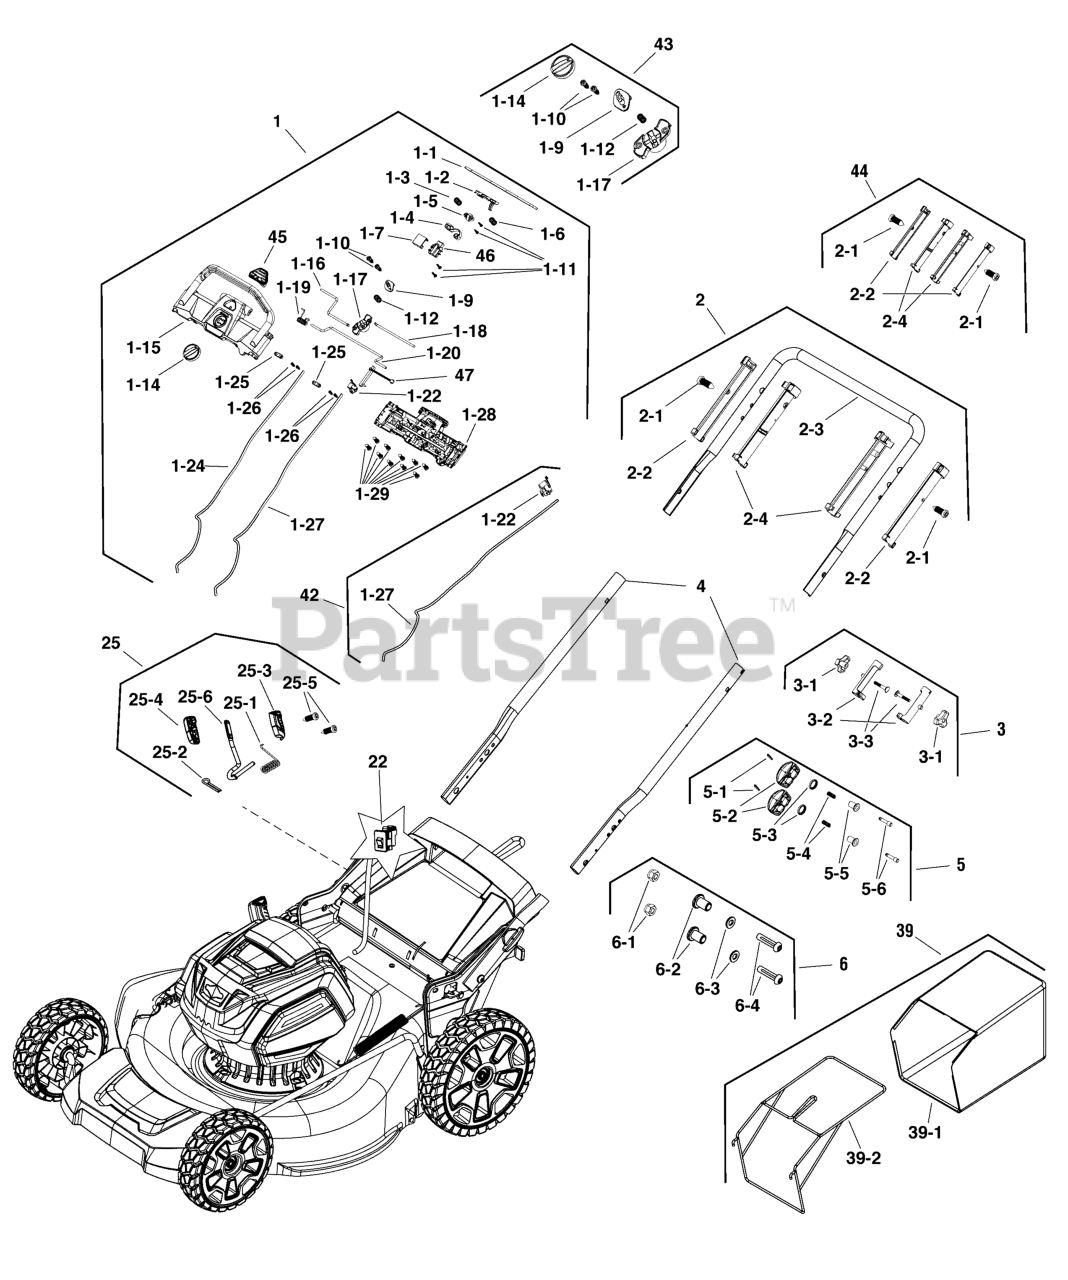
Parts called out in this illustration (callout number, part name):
1	PANEL ASSEMBLY
1-1	ROD, Personal Pace
1-2	SWITCH
1-3	SPRING
1-4	SPRING, Pivot
1-5	DISC, Tension
1-6	SPRING
1-7	INSERT
1-9	PIVOT, Control
1-11	SCREW
1-12	SPRING, Compression
1-14	KNOB, Control
1-15	PANEL, Upper
1-16	LEVER, Lock, RH
1-17	PIVOT, Lock
1-18	LEVER, Lock, LH
1-19	SPRING, Torsion
1-20	LEVER, Control
1-22	SWITCH
1-24	CABLE, Blade
1-25	RETAINER
1-27	CABLE, Drive
1-28	PANEL, Lower
1-29	HINGE
2	KIT, Upper Handle
2-1	HINGE
2-2	SLIDE, Outer
2-3	HANDLE, Upper
2-4	SLIDE, Inner
3	KIT, Mounting Hardware
3-2	SLEEVE
3-3	BOLT
4	LOWER HANDLE ASSEMBLY
5	KIT, Knob, Lower Handle
5-1	PIN
5-2	KNOB, Lower Handle
5-3	GASKET
5-4	SPRING
5-5	INSERT
5-6	POST
6	KIT, Hardware, Lower Handle
6-2	INSERT
6-3	WASHER, Flat
6-4	BOLT
22	KIT, Inverted Switch
25	KIT, Handle, Height Adjust
25-1	SPRING
25-2	PIN, Cotter
25-3	HOUSING, Left
25-4	HOUSING, Right
25-6	ROD, Adjusting
39	KIT, Grass Catcher
39-1	BAG, Grass Catcher
39-2	FRAME
42	KIT, Drive Cable
43	KIT, Control Knob
44	KIT, Slides
45	KIT, Start Button
46	SWITCH, Operator Presence
47	SWITCH, Speed Control
